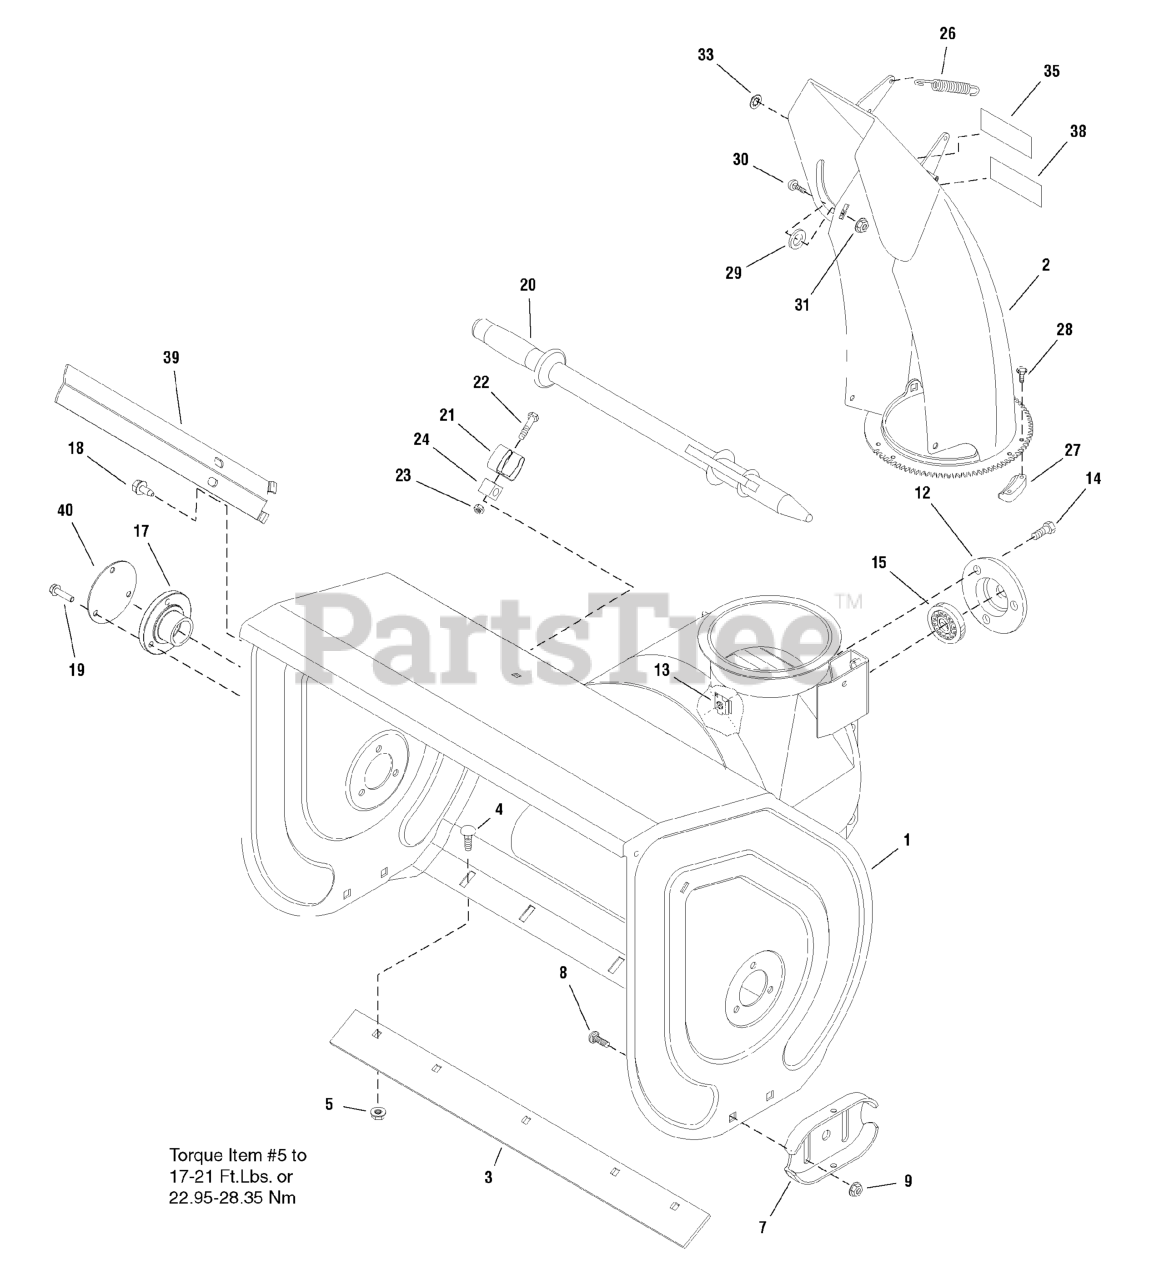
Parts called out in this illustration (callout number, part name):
1	AUGER HOUSING ASSEMBLY, 30" Auger
2	CHUTE & DEFLECTOR ASSEMBLY
3	BLADE, Scraper, 30"
4	CARRIAGE BOLT, 5/16-18 x 5/8 G5
5	NUT, Hex Flange Two-Way Lock, 5/16-18
7	SKID, Shoe Reversible
8	CARRIAGE BOLT, 3/8-16 x 3/4 G5
9	NUT, Hex Flange ESNA, 3/8-16
12	BEARING, Retainer
13	RETAINER, Nut, 5/16-18
14	SCREW, Hex Whiz Lock Flange, 5/16-18 x 3/4
15	BEARING, Greased
17	BUSHING, Auger Flange
18	SCREW Hex Head, .312-18 x 3/4
19	SCREW, Hex Washer Head Taptite 5/16-18 x 1-1/4
20	STICK, Cleanout w/Brush
21	CLIP, Retainer
22	SCREW, Hex Washer Head Slot
23	NUT, Hex Lock 10-24 w/Nylon Insert
24	BLOCK, Universal Pivot
26	SPRING, Extension
27	RETAINER, Spout
28	CAPSCREW, Hex Washer Head Taptite, #10C x 5/8 GR5 BZ
29	WASHER, Nylon, .388 x 1.12 x .030
30	CARRIAGE BOLT, 5/16-18 x 3/4 G5
31	NUT, Hex Flange ESNA, 5/16-18
33	NUT, Push for .312 DIA Stud Capped .625OD
35	DECAL, Hinge Upper
38	DECAL, Hinge Lower
39	DRIFT CUTTER
40	COVER, Bushing
